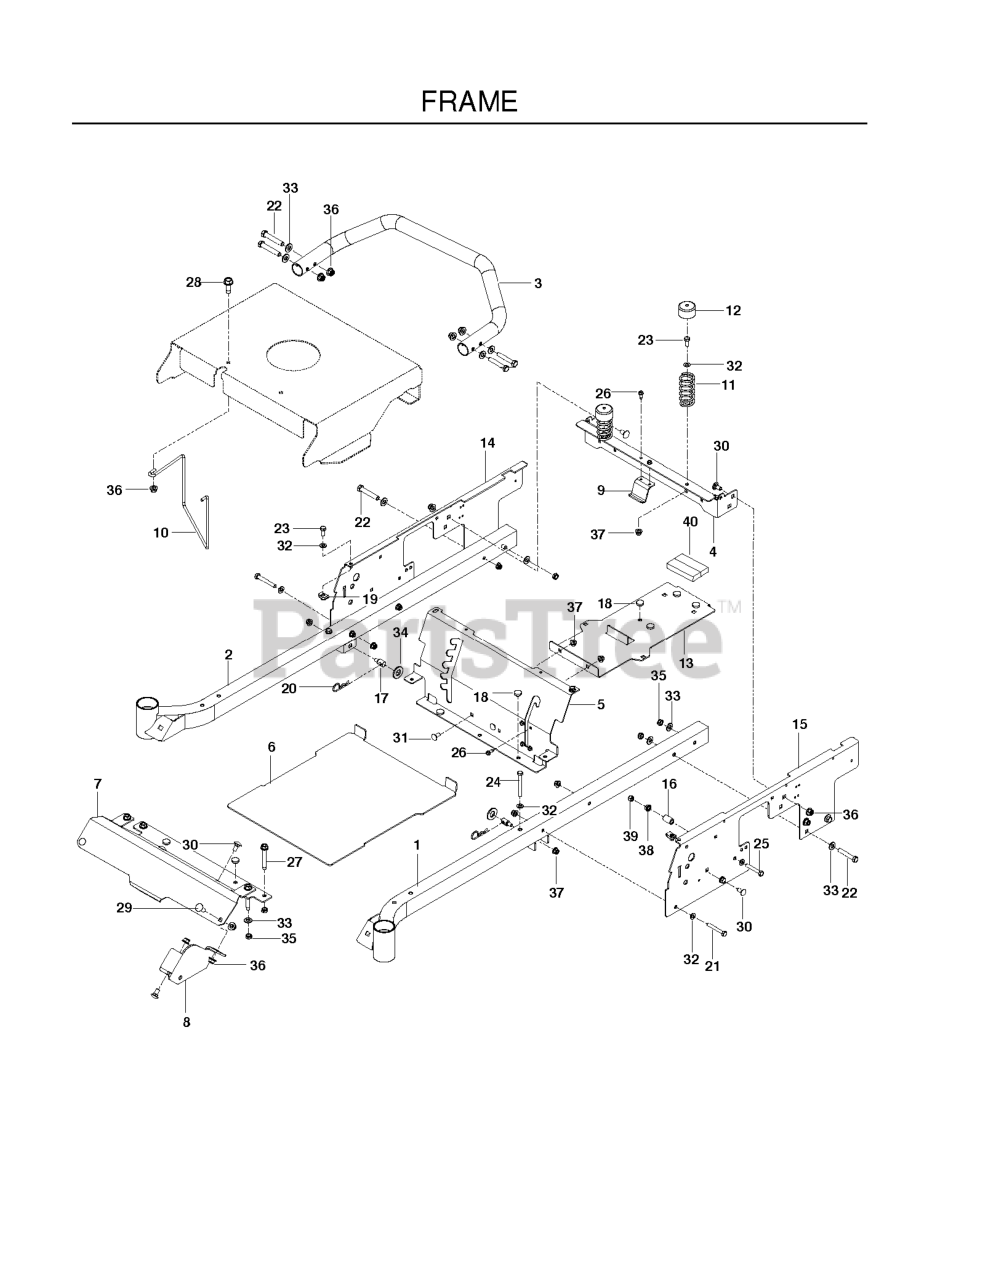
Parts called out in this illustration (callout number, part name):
1	FRAME TUBE, LH, ORG
2	FRAME TUBE, RH, ORG
3	IMPACT BAR, ORG
4	SEAT SUPPORT, REAR ORG
5	PANEL.SEAT.SUPPORT.ORANGE
6	PAN, FLOOR W/DECALS, HUS
7	FOOT REST, ORG
8	BRACKET, FRONT DECK, BLK
9	HOLDING DEVICE, FUEL TANK, BLK
10	KEEPER, BELT ENGINE
11	SEAT SPRING
12	SPRING CAP
13	SUPPORT, TANK/BATT, BLK
14	PLATE.RH.SIDE.ORANGE
15	PLATE.LH.SIDE.ORANGE
17	STUD.FASTNER.W/ANTI-ROTATE
18	GROMMET, BUMPER
19	U-CLIP 5/16-18 NUT RETAINER
20	HAIRPIN #4
22	HCS 3/8C X 2 1/4
23	HCS 5/16C X 3/4
24	HCS 5/16C X 2-3/4
25	HCS 5/16-18X2
26	SCREW 1/4 X 5/8
27	ENGINE BOLT, SPECIAL
28	BOLT 3/8-16 X 1.0
29	RHSNB 3/8C X 1
30	RHSNB 3/8-16 X 3/4 GR5 ZD
31	BOLT 5/16C X 3/4" CARRIAGE
32	FLAT WASHER 5/16 SAE
33	WASHER 3/8 SAE FLAT
34	WASHER 5/8 FLAT
35	NUT HEX 3/8-16 NYLON, THIN
36	NUT 3/8-16 HEX FLG NYLOC ZD
37	5/16-18 NYLOC FLANGE NUT
38	NUT 5/16C WHIZ
39	NUT 5/16 NYLOC
40	FOAM STRIP, FUEL TANK
